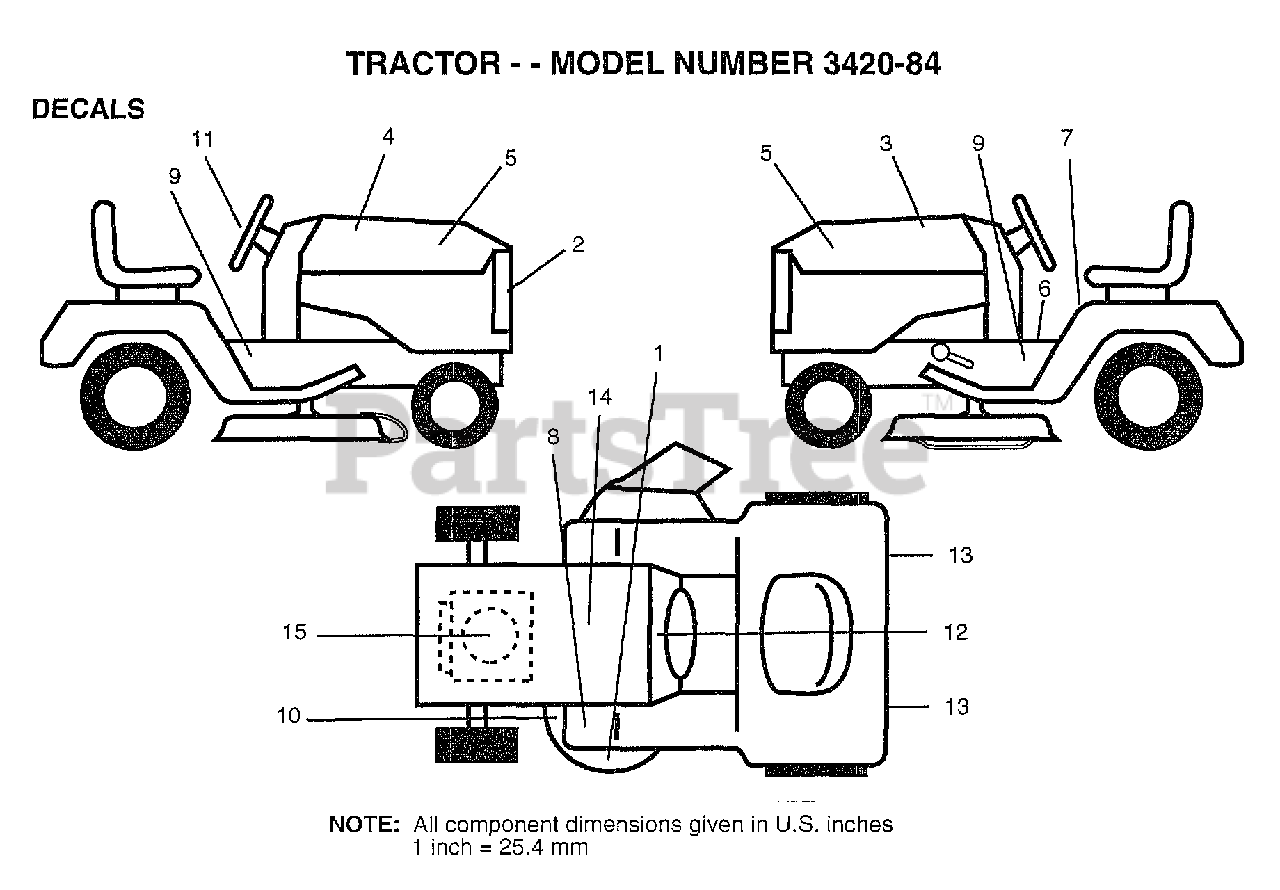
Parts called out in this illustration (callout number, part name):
2	GRILL DECAL
3	HOOD DECAL LH
5	NAMEPLATE LOGO
6	DECAL BRAK PARK
7	"DECAL DANGER,FEND"
9	DECAL.CHASSIS
10	"DECAL-SCHEM,BELT"
12	"DECAL-OPER,GEAR D"
13	REFLECTOR-TAIL YT
14	DECAL.BATRY.3-3908
15	DECAL, HP ENGINE
